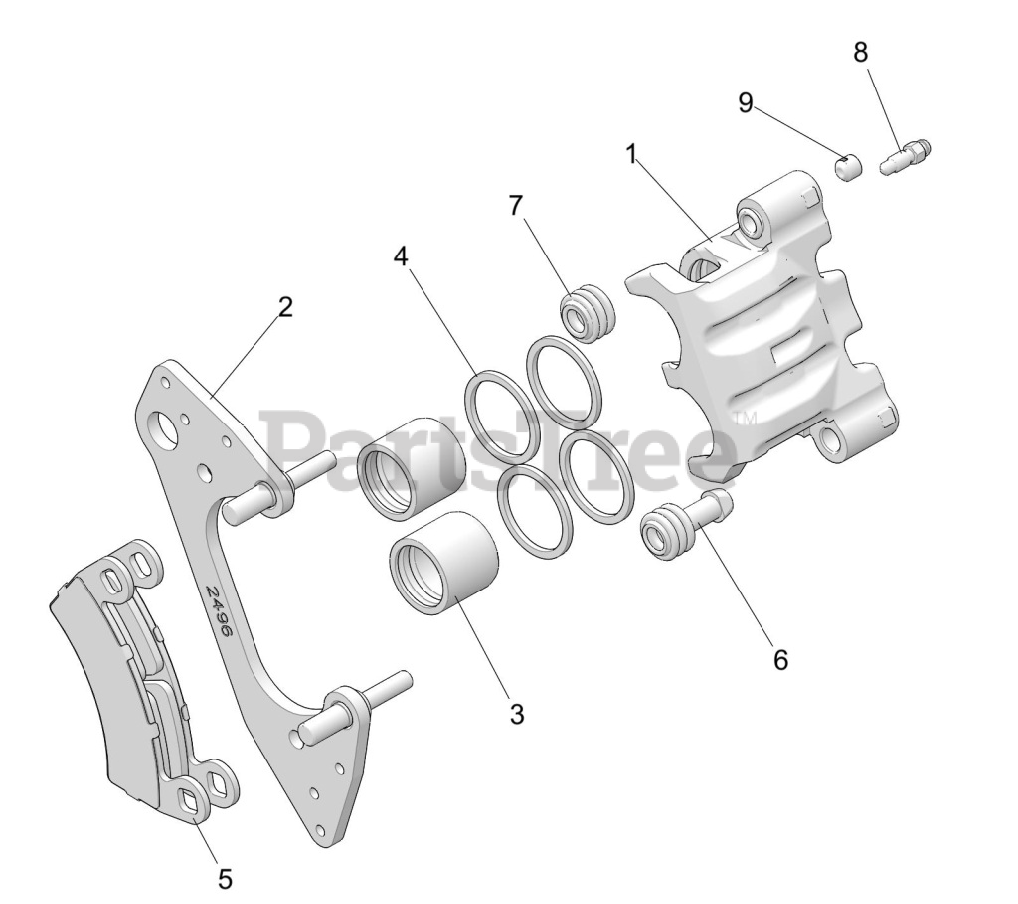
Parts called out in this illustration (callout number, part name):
1	ASM-BRK-CAL-L-DB1-3/8-GROOVED
1	ASM-BRK-CAL-R-DB1-3/8-GROOVED
2	ASM-CAL/MNT-DB-1-3/8-METRIC
3	PISTON-BRAKE-1.375-AL-GROOVED
4	SEAL-CALIPER-INNER-1.375"
5	KIT-ASM-PAD-BRAKE-DB-1.375
6	BOOT-PIN BUSHING
7	BOOT-PIN SEAL
8	SCR-M7X1.0-BLEEDER-OLIVE D
9	SCR-M10X1.0X8-SOC SET-OD
